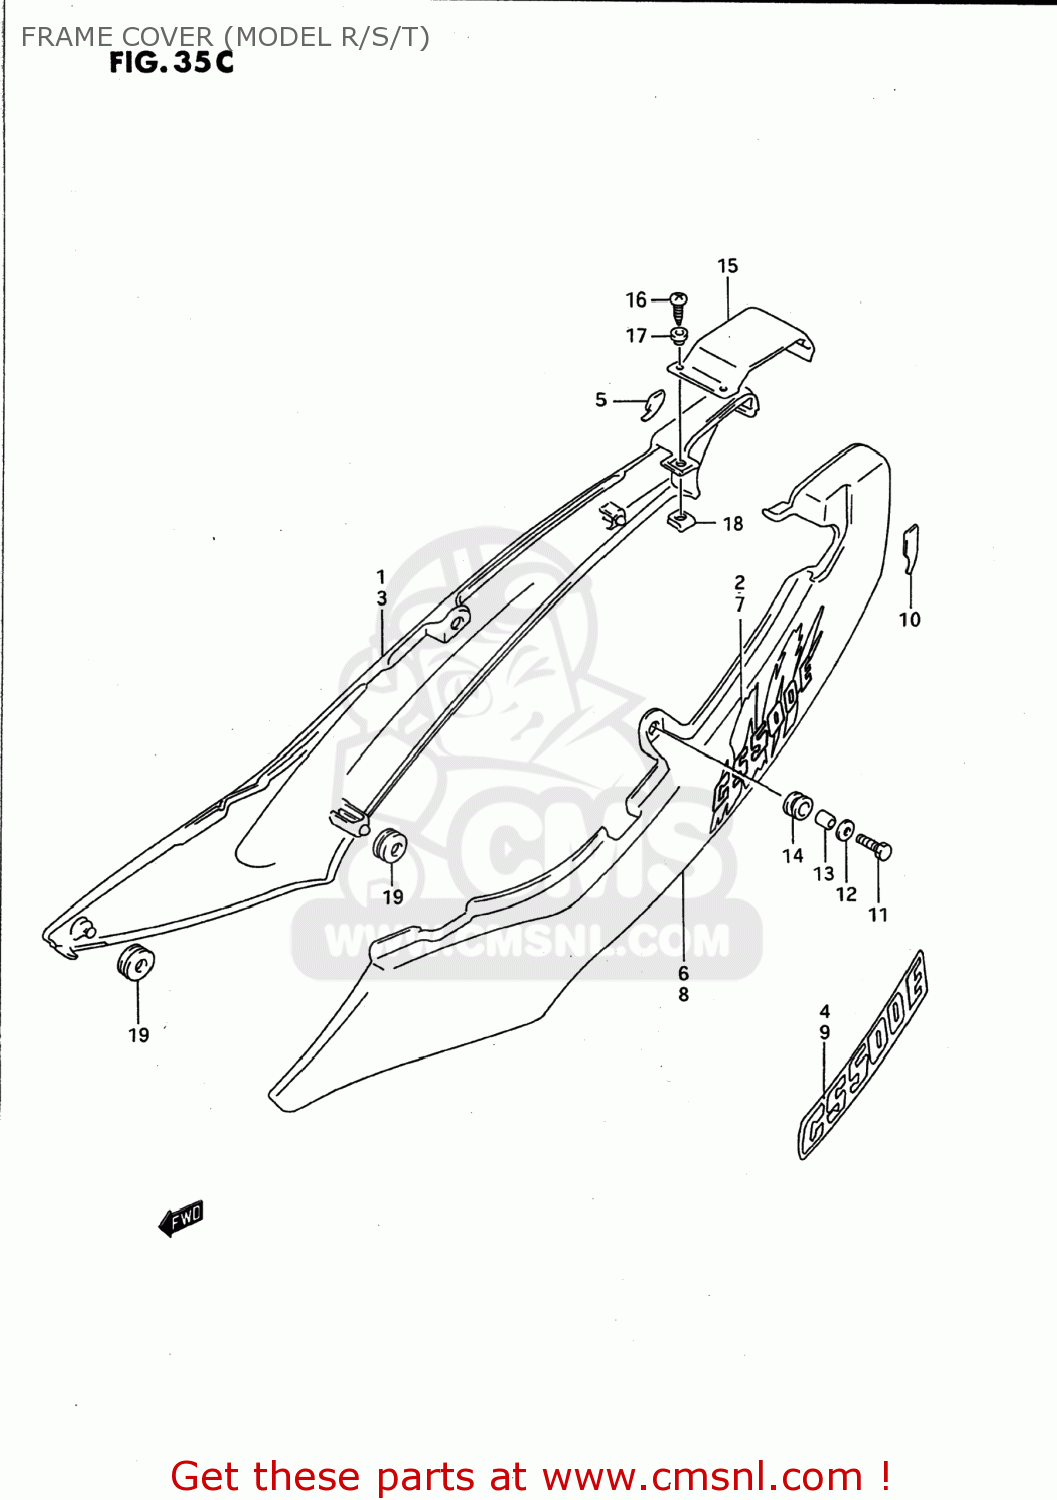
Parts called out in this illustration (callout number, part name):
1	COVER,FRAME,RIGHT
2	EMBLEM,FRAME COVER
3	COVER COMP,FRAME,RIGHT
4	EMBLEM,FRAME COVER
5	PROTECTOR,FRAME COVER,R
6	COVER,FRAME,LEFT
7	EMBLEM,FRAME COVER
8	COVER,FRAME,L(RED)
9	EMBLEM,FRAME COVER
10	PROTECTOR,FRAME COVER,L
11	BOLT(6X20)
12	WASHER
13	SPACER (6.1X9X9)
14	CUSHION
15	COVER,FRAME CTR
16	SCREW L:12
17	WASHER(5.2X14X1.5)
18	NUT
19	CUSHION
